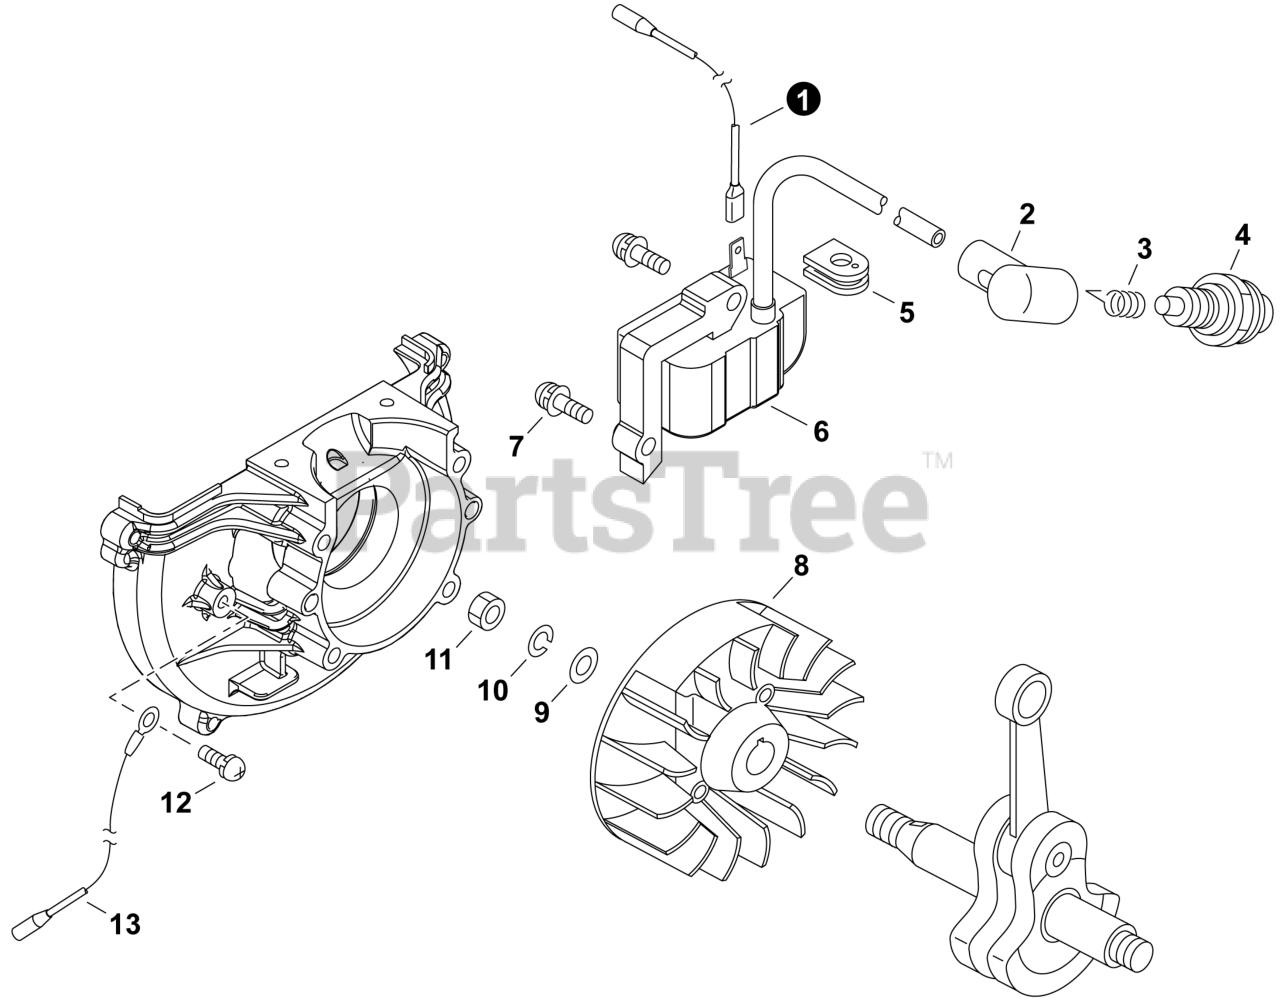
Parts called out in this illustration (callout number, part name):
2	CAP, SPARK PLUG
3	TERMINAL, SPARK PLUG
4	SPARK PLUG - BPMR7A
6	COIL, IGNITION
7	SCREW 5x20
8	FLYWHEEL
9	WASHER 10.5x18x1.6
10	WASHER, SPRING 10
11	NUT 10x1.25
12	SCREW 5x10
13	LEAD - GROUND
